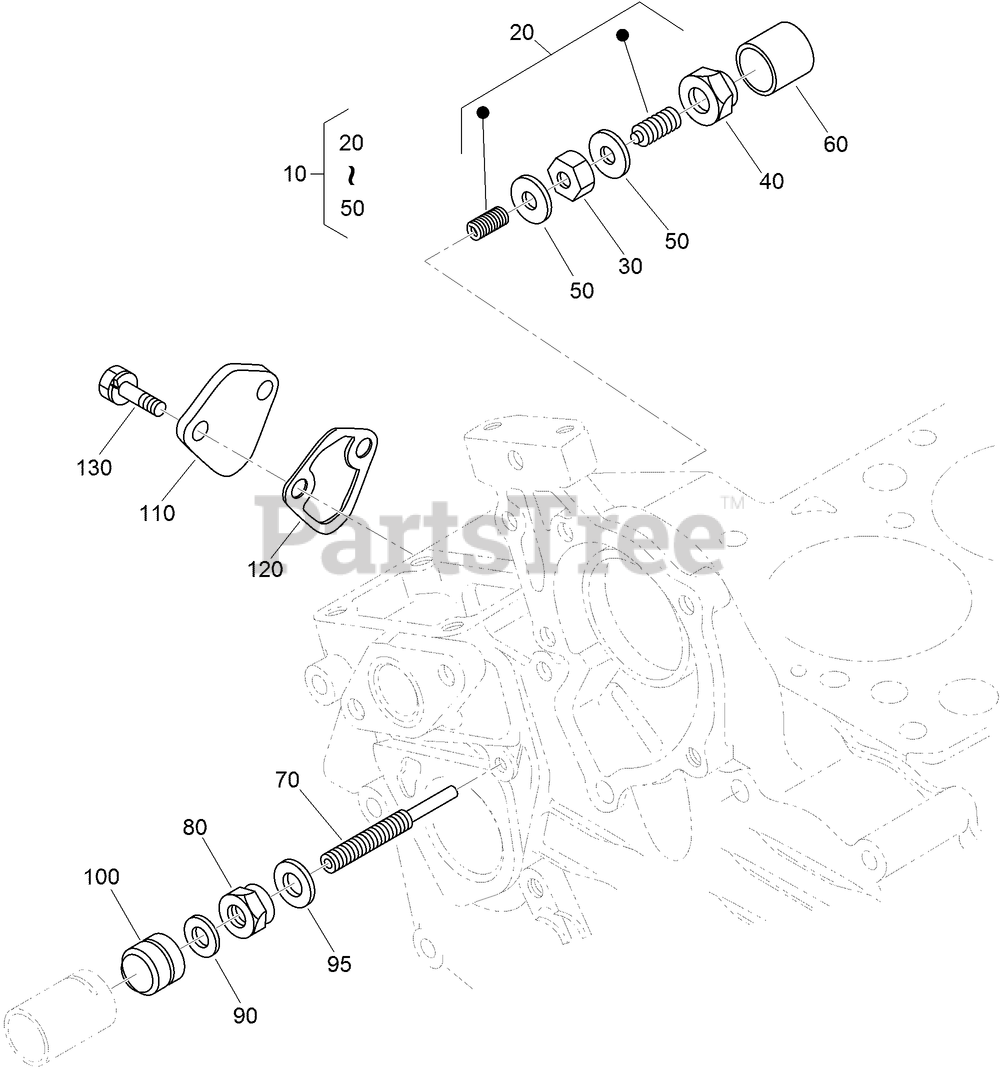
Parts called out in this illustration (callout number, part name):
10	IDLE APPARATUS ASM
20	ADJUSTING BOLT ASM
40	NUT-CAP
50	GASKET
70	BOLT-ADJUSTING
80	NUT-LOCK
90	GASKET
95	GASKET
100	NUT-CAP
110	COVER
120	GASKET-PUMP, FUEL
